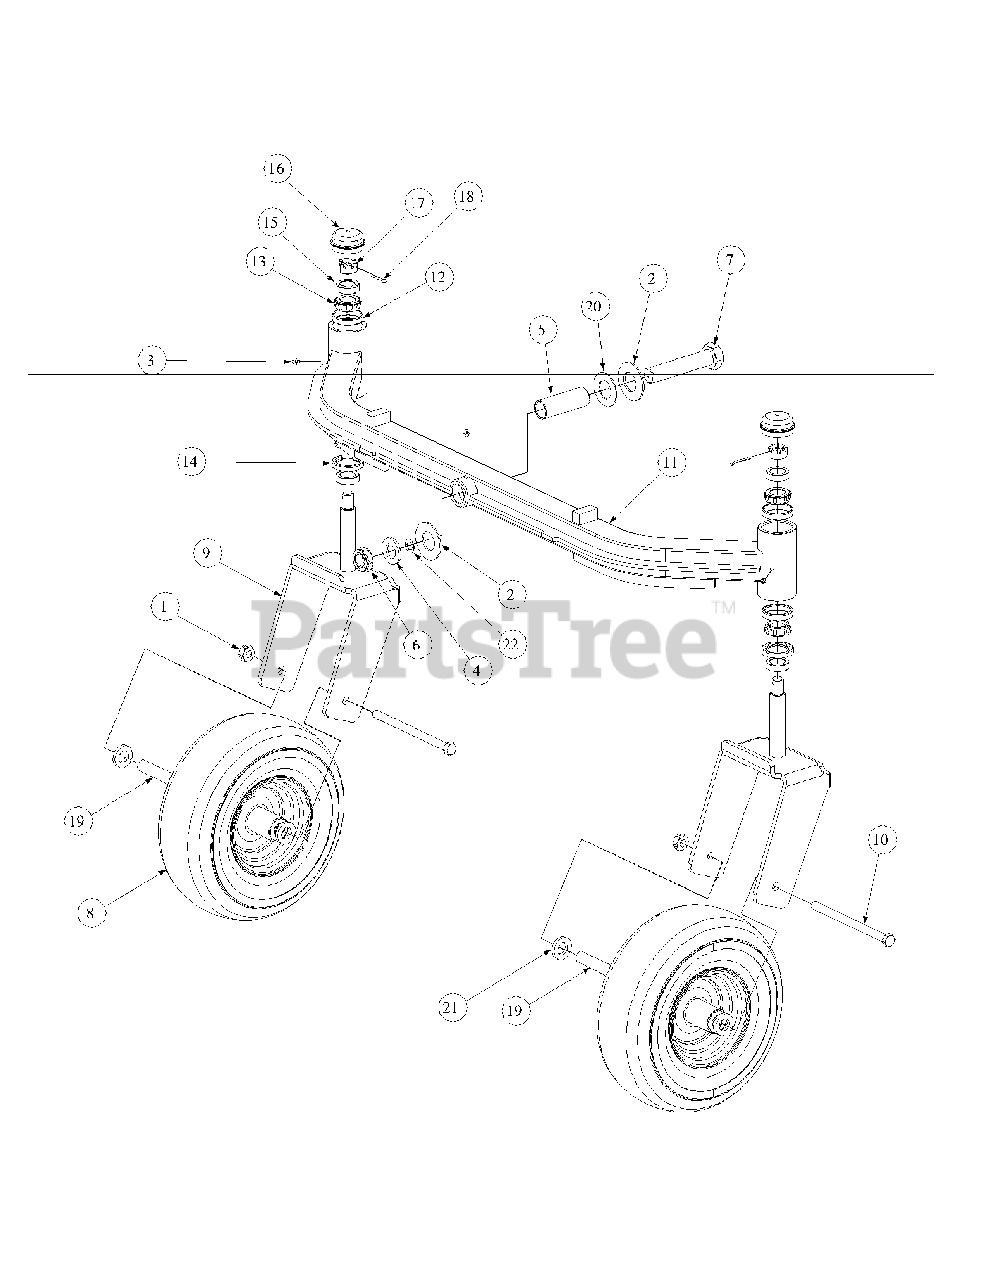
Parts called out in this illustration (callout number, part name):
1	Nut, 1/2-20, Center Lock
2	Bell Washer, 1.25 ID x 2.5 OD x .180
3	Grease Fitting
4	Special Washer
5	Spacer, 1.005 ID x 1.25 OD x 3.6
6	Nut, Jam, 1.0-14, Insert Lock
7	Hex Cap Screw, 1-14 x 5.0
8	Wheel, 13 x 6.50 x 6, White
9	Yoke, Caster Wheel
10	HHCS, 1/2-20, 7.50
11	Front Axle Assembly
12	Cup Bearing
13	Bearing Cone
14	Seal
15	Ring Seal
16	Grease Cap, 1.986 OD
17	Slotted Nut, 3/4-16
18	Cotter Pin, 5/32, 1.25
19	Wheel Spacer
20	Flat Washer, 1.25 ID x 2.25 OD x .075
21	Spacer, .812 ID x .218LG
22	Retainer Extension, Self Locking
